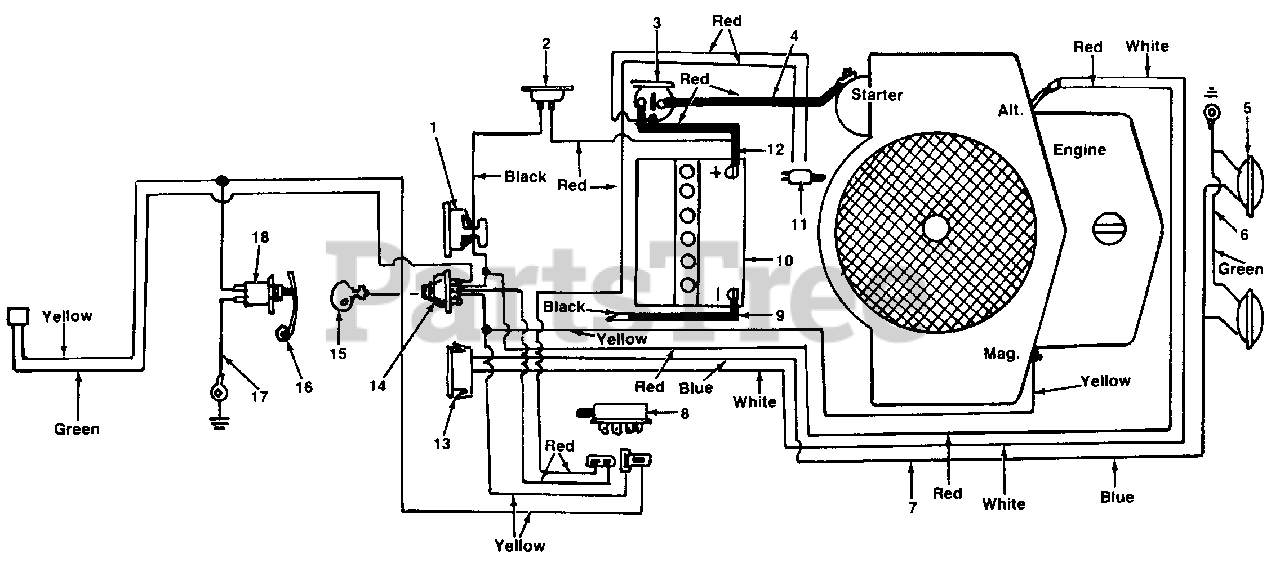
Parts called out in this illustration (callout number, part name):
1	Ammeter
2	Circuit Breaker
3	Solenoid
4	Wire
5	Headlight
6	Ground Wire
7	Wire Harness
8	Safety Switch
9	6 Ga. Black Wire
10	Battery 12V
11	Safety Switch
13	Light Switch
14	Ignition Switch
15	Ignition Key
16	Spring Lever
17	Electric Wire
18	Safety Switch
